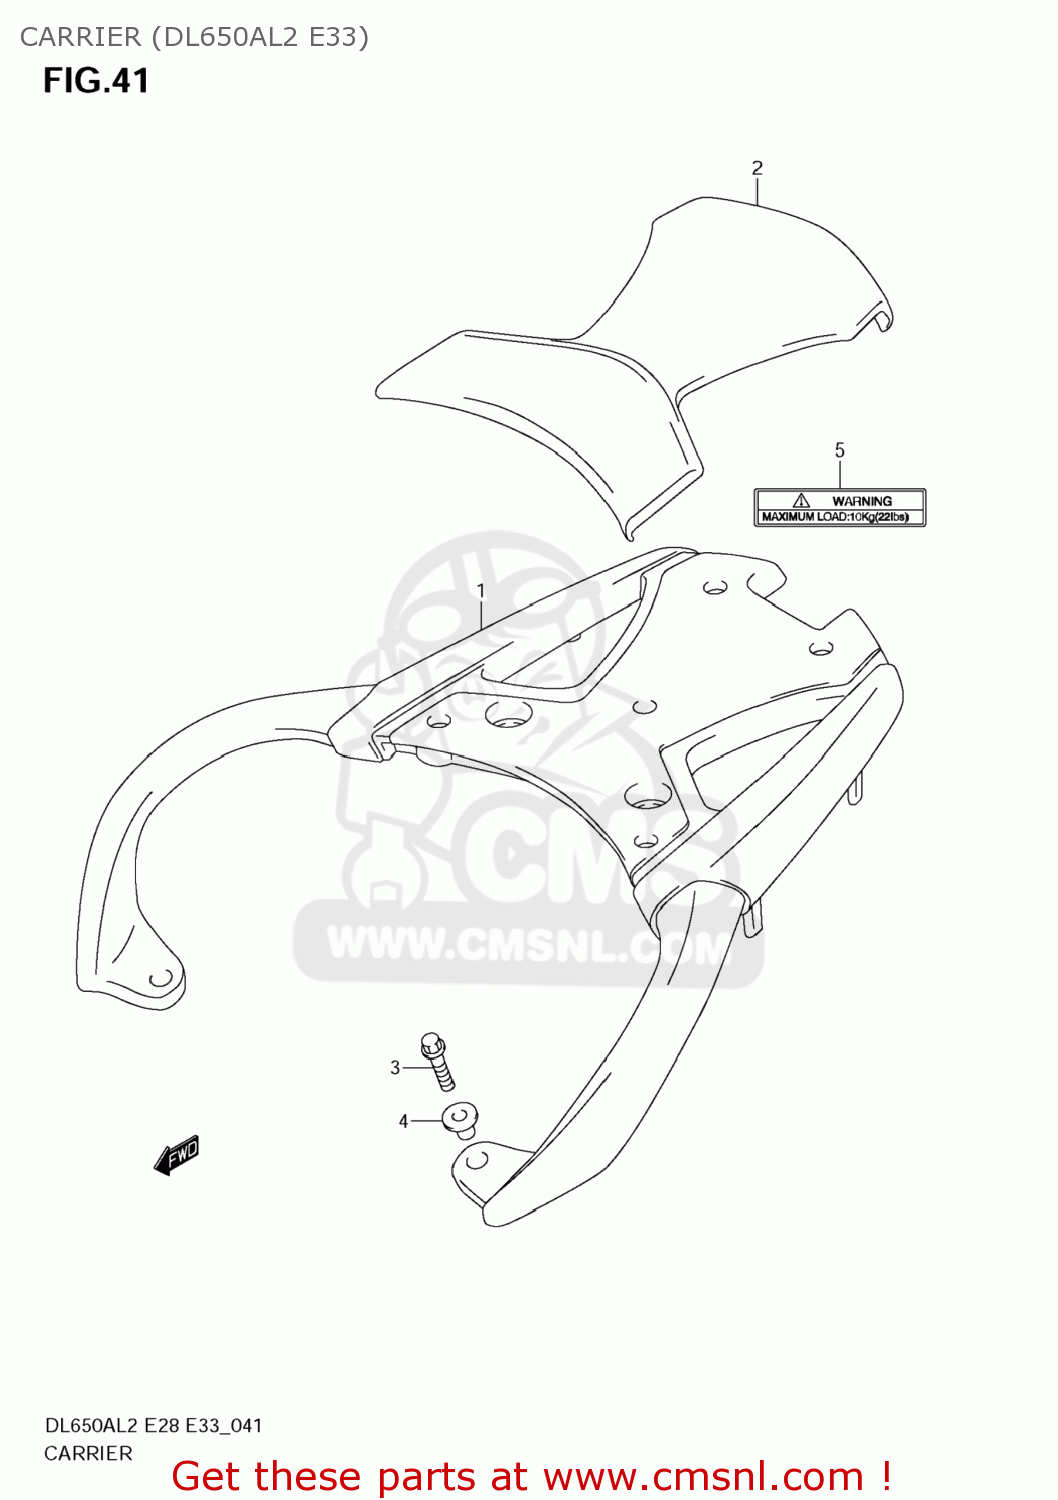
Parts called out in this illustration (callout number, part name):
1	CARRIER,SPORT
2	MAT,SPORT CARRIER
3	BOLT(8X35)
4	WASHER
5	LABEL,WARNING LUGGAGE CARRIER
